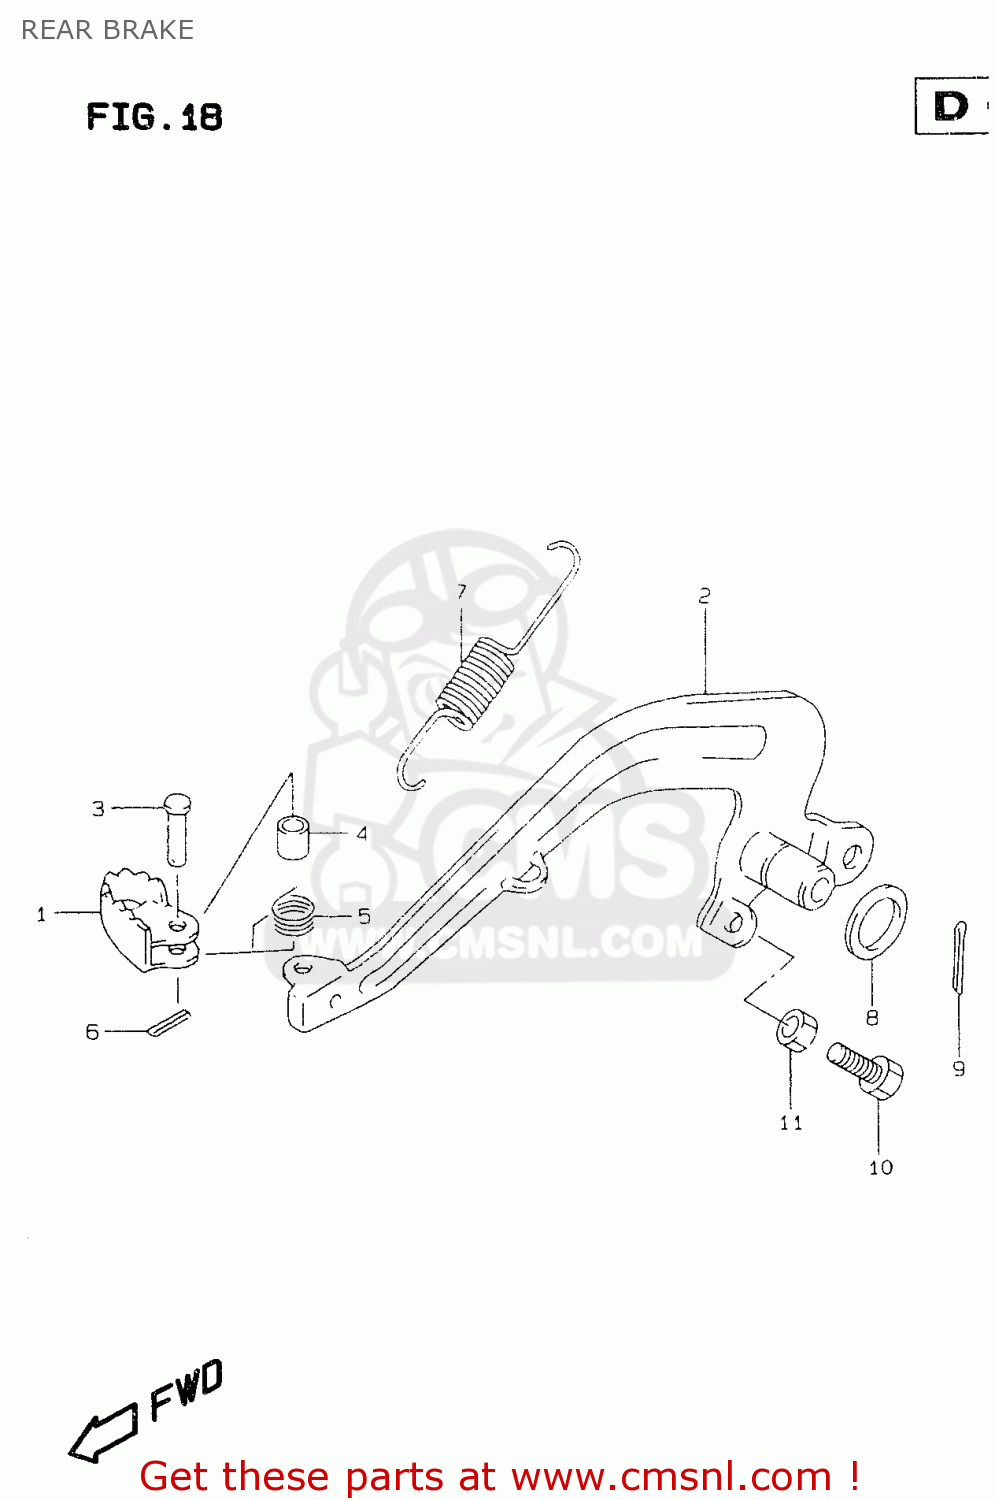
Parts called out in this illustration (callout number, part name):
1	PEDAL,BRAKE
2	ARM,BRAKE PEDAL
3	PIN
4	SPACER(6.5X9X6.5)
5	SPRING
6	PIN
7	SPRING
8	WASHER(15.5X26X2.3)
9	PIN, COTTER
10	SCREW(6X23)
11	NUT 6MM
